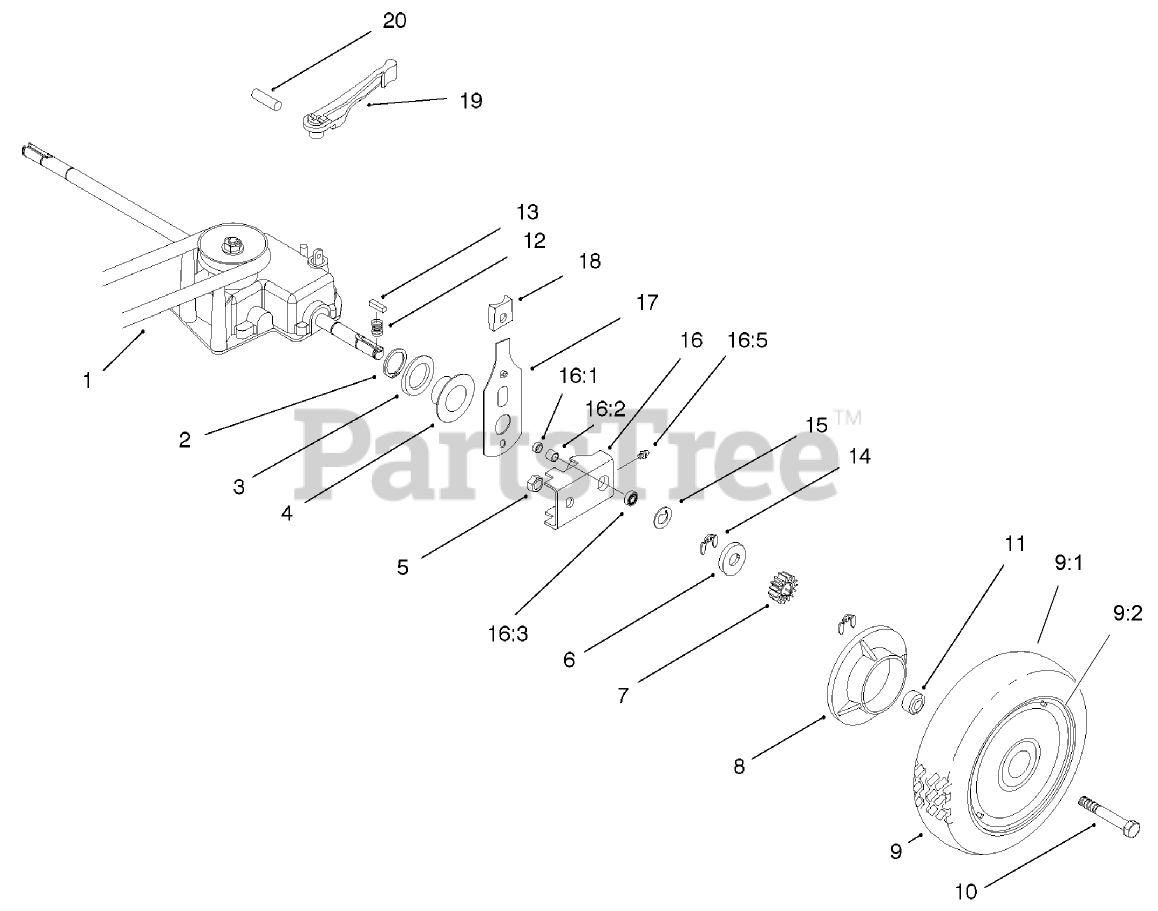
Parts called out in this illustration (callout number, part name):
1	V-BELT
2	RING-RETAINING
3	WASHER
4	CAP-END
5	NUT-LOCK, CONE
6	WASHER-THRUST, OUTER
7	GEAR-PINION
8	COVER-WHEEL
9:2	Wheel ASM
10	SCREW-HH
11	SPACER-COVER, WHEEL
12	SPRING-COMPRESSION
14	RING-RETAINING
15	WASHER-THRUST, OUTER
16	PIVOT ARM ASM
16:1	SEAL-OIL
16:3	BEARING-WHEEL
17	REAR SPRING ARM ASM
18	KNOB-ARM
19	LEVER-SHIFT
20	PIN-SPRING
